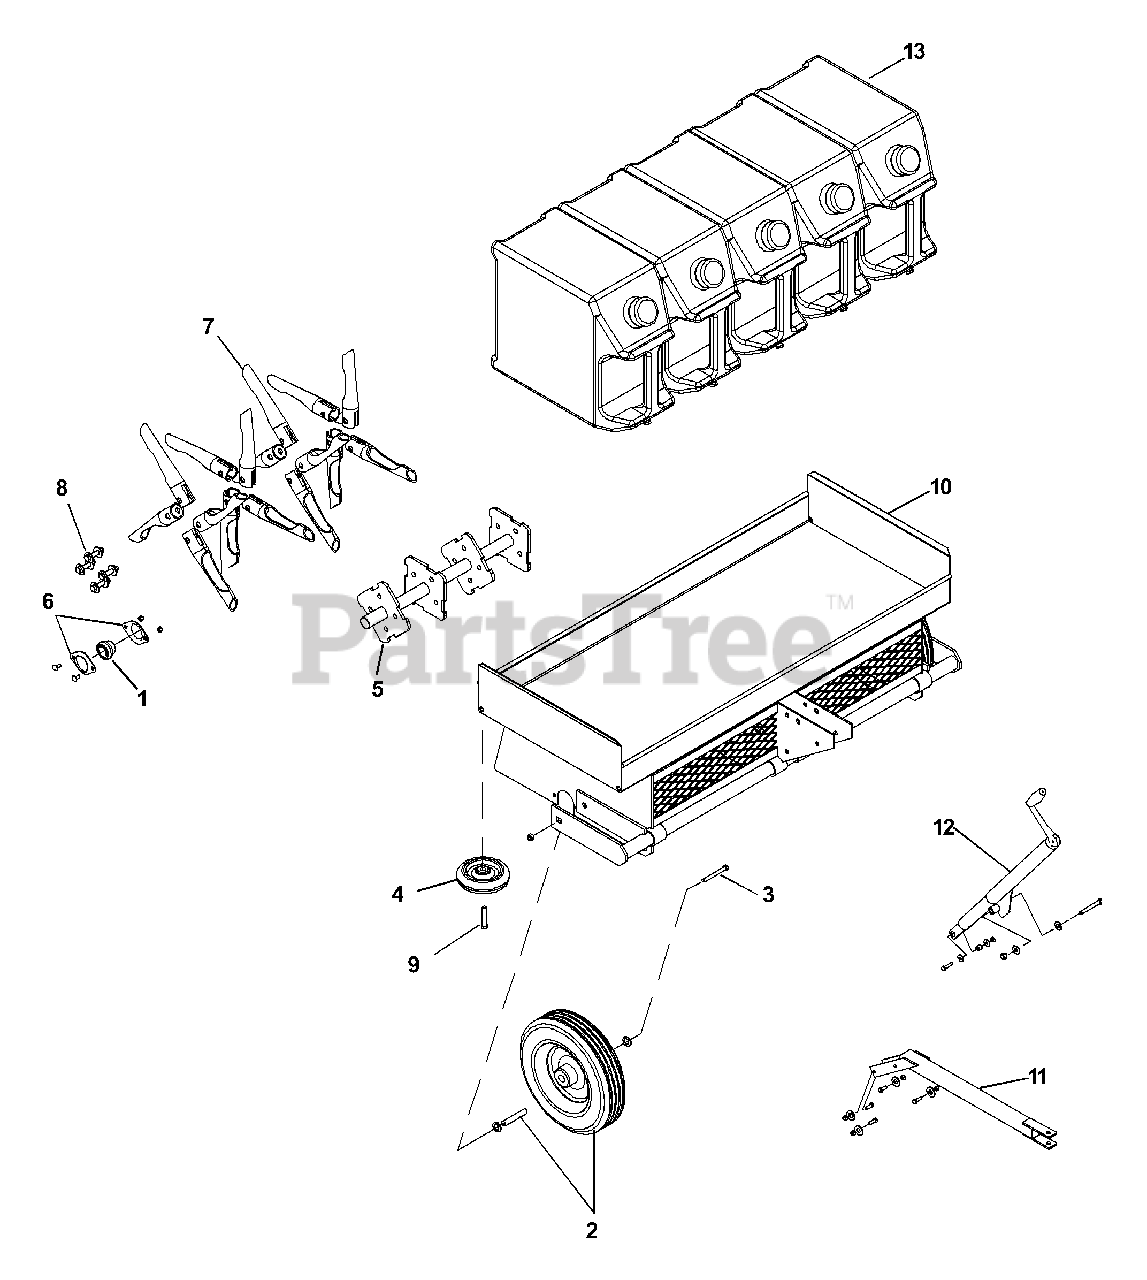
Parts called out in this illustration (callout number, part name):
1	BEARING W/COLLAR
2	WHEEL, 12" X 3" W/ROLLER BEARING
3	BOLT KIT FOR 12" WHEELS
4	TILT WHEEL
6	STAMPING KIT, FOR 1" BEARING
7	TINE SET (16 PER ROTOR)
8	FASTENER KIT, CORING TINE SET
9	SCREW, 1/2-13 X 3
10	CHASSIS WELDMENT
11	TOW BAR W/ BOLT KIT
12	JACK W/ BOLT KIT
13	WATER TANKS (SET OF 5)
